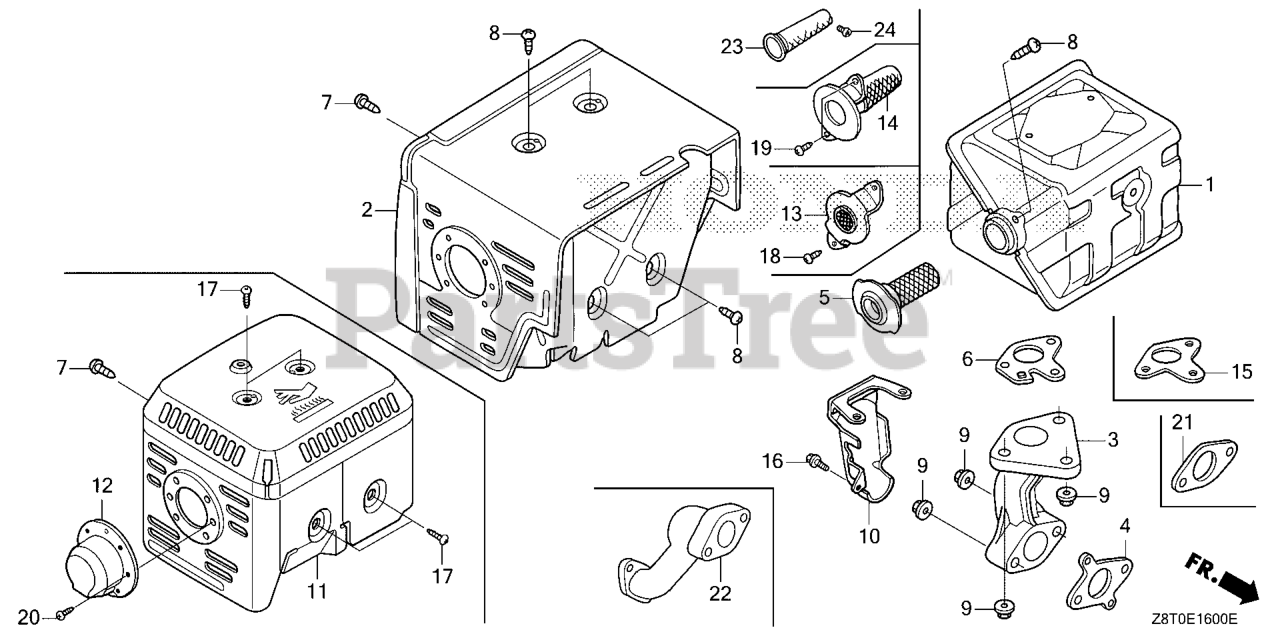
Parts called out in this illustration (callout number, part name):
1	MUFFLER
4	GASKET, EX. PIPE
7	SCREW, TAPPING (6X10)
9	NUT, FLANGE (8MM)
10	PROTECTOR, EX. PIPE
11	PROTECTOR, MUFFLER
12	CAP, MUFFLER
13	FLANGE, BAFFLE
14	ARRESTER, SPARK
15	GASKET, MUFFLER (NIPPON LEAKLESS)
15	GASKET, MUFFLER (THAI LEAKLESS)
16	BOLT, FLANGE (6X12) (CT200)
17	SCREW, TAPPING (5X8)
18	SCREW, TAPPING (5X8)
19	SCREW, TAPPING (5X8)
20	SCREW, TAPPING (4X6) (TO INSTALL OPTIONAL SPARK ARRESTER)
